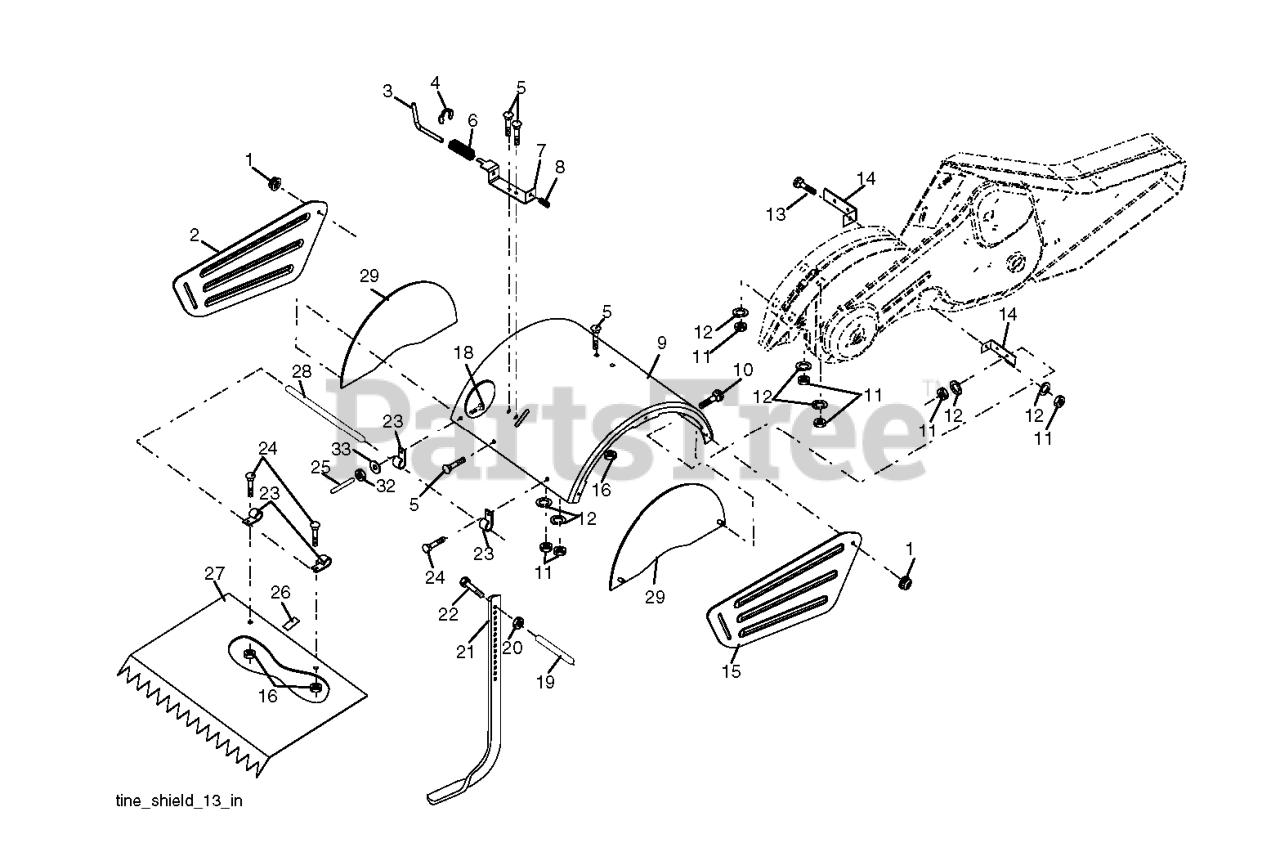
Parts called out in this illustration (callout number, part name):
1	NUT LOCK HEX FLANGE 5/16-18
2	SHIELD
3	STAKE PIN TI
4	RING, KLIP
5	BOLT, RDHD SQNK 5/16-18 X 3/4
7	BRACKET.LATCH.STAKE.3.20.BLACK
8	SPRING CRT
9	SHIELD.TINE.CRT.ORANGE
12	WASHER.LOCK.HVY.HLCL.SPR.5/16
13	BOLT.CARRIAGE.5/16-18
14	BRACKET.TINE.SHIELD.TILLER
15	SIDE SHIELD RH
16	NUT T
20	NUT.HEX.3/8-16UNC
21	STAKE.DEPTH.16.CRT.BLACK
22	BOLT.375-16
25	VINYL CAP TI
26	PAD IDLER TI
27	SHIELD LEVELING
28	PIN.HINGE.TILLER
29	SHIELD SIDE
32	NUT
33	LOCKWASHER
